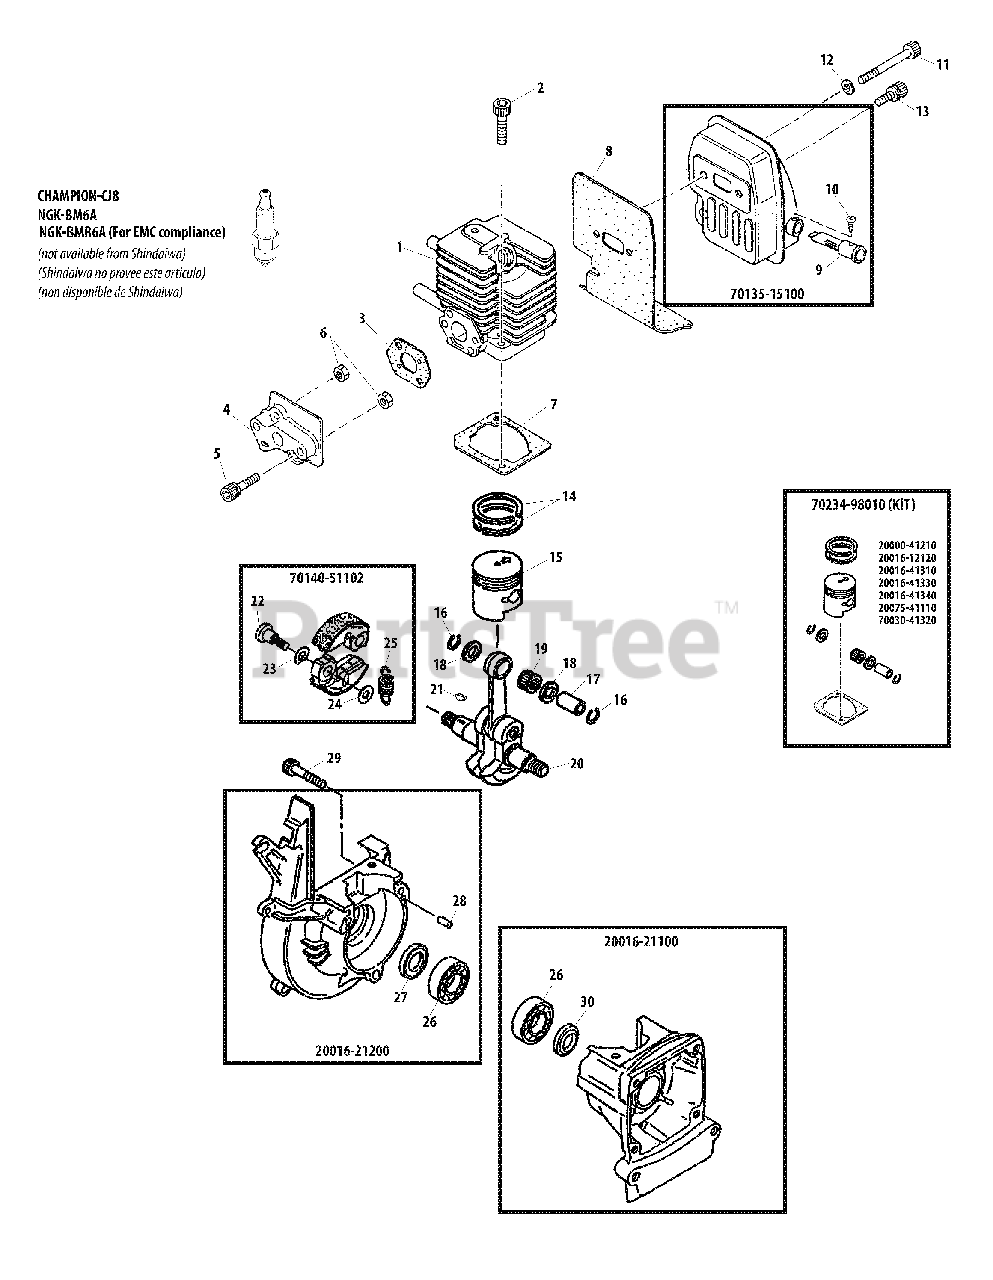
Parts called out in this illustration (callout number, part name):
1	CYLINDER
2	SCREW - 5X25
3	GASKET
4	INSULATOR
5	SCREW - 5X30
7	GASKET, CYLINDER
8	SHIELD, EXHAUST
9	SCREEN, SPARK ARRESTOR
10	SCREW - 3X6
11	SCREW - 5X50
12	WASHER - 5
13	SCREW - 5X12
14	RING, PISTON
15	PISTON
16	RING, RETAINING
17	PIN, PISTON
18	WASHER, THRUST
19	BEARING, NEEDLE
20	CRANKSHAFT ASSY
21	KEY - 3X10
22	BOLT, CLUTCH
23	WASHER - SPRING
24	WASHER - 6
25	SPRING, CLUTCH
26	BEARING, BALL - 6001C3
27	SEAL, OIL - 12
28	PIN - LOCATING
29	SCREW - 5X25
30	SEAL, OIL
20016-21100	CRANKCASE ASSY - REAR
20016-21200	CRANKCASE ASSY - FRONT
70135-15100	MUFFLER ASSY
70140-51102	CLUTCH ASSY
70234-98010	PISTON ASSY
